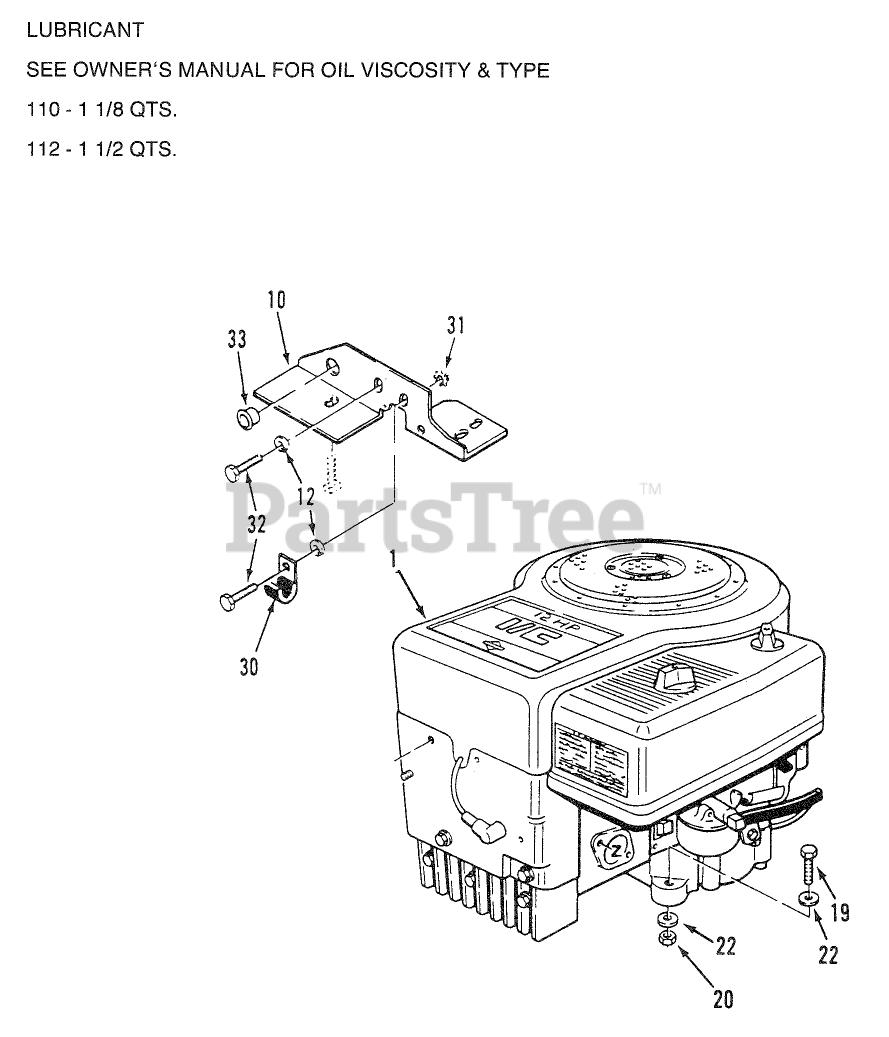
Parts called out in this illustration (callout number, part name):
1	Engine-10 HP Briggs and Stratton I.C. Model 256707 Type 0117 01
10	BRACKET-ENGINE HE R
12	Lockwasher
30	CLIP
31	Washer-Lock
33	BUSHING-NYLON 1.093
